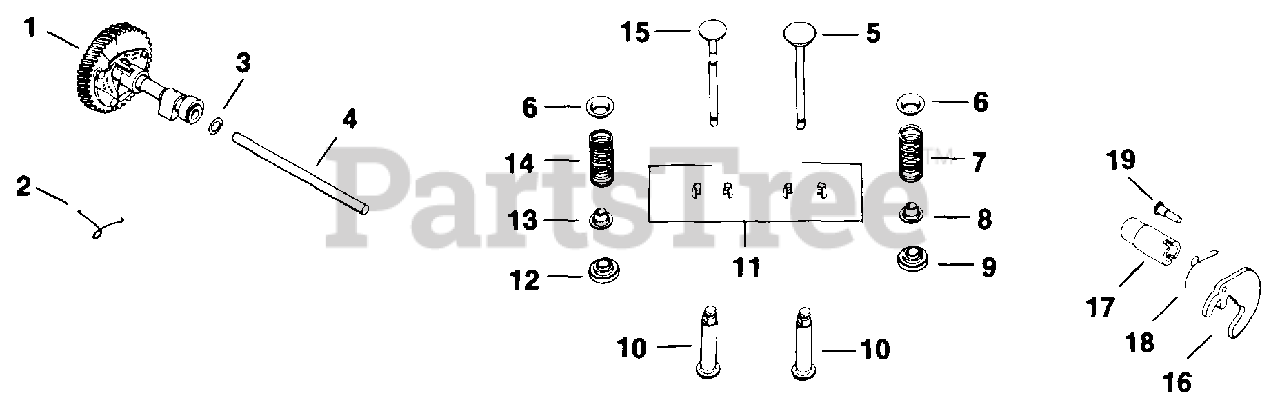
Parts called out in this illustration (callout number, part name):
1	CAMSHAFT - DISCONTINUED
2	SPRING, ACTUATING-DISCONTINUED
3	SPACER (.005")
3	SPACER (.010")
4	PIN - USE 47 380 09
5	VALVE, INTAKE
6	RETAINER, SPRING
7	SPRING, EXHAUST VALVE
8	RETAINER, VALVE SPRING
11	Kit, retainer
13	RETAINER, VALVE SPRING
14	SPRING, EXHAUST VALVE
18	SPRING - DISCONTINUED
19	PIN
